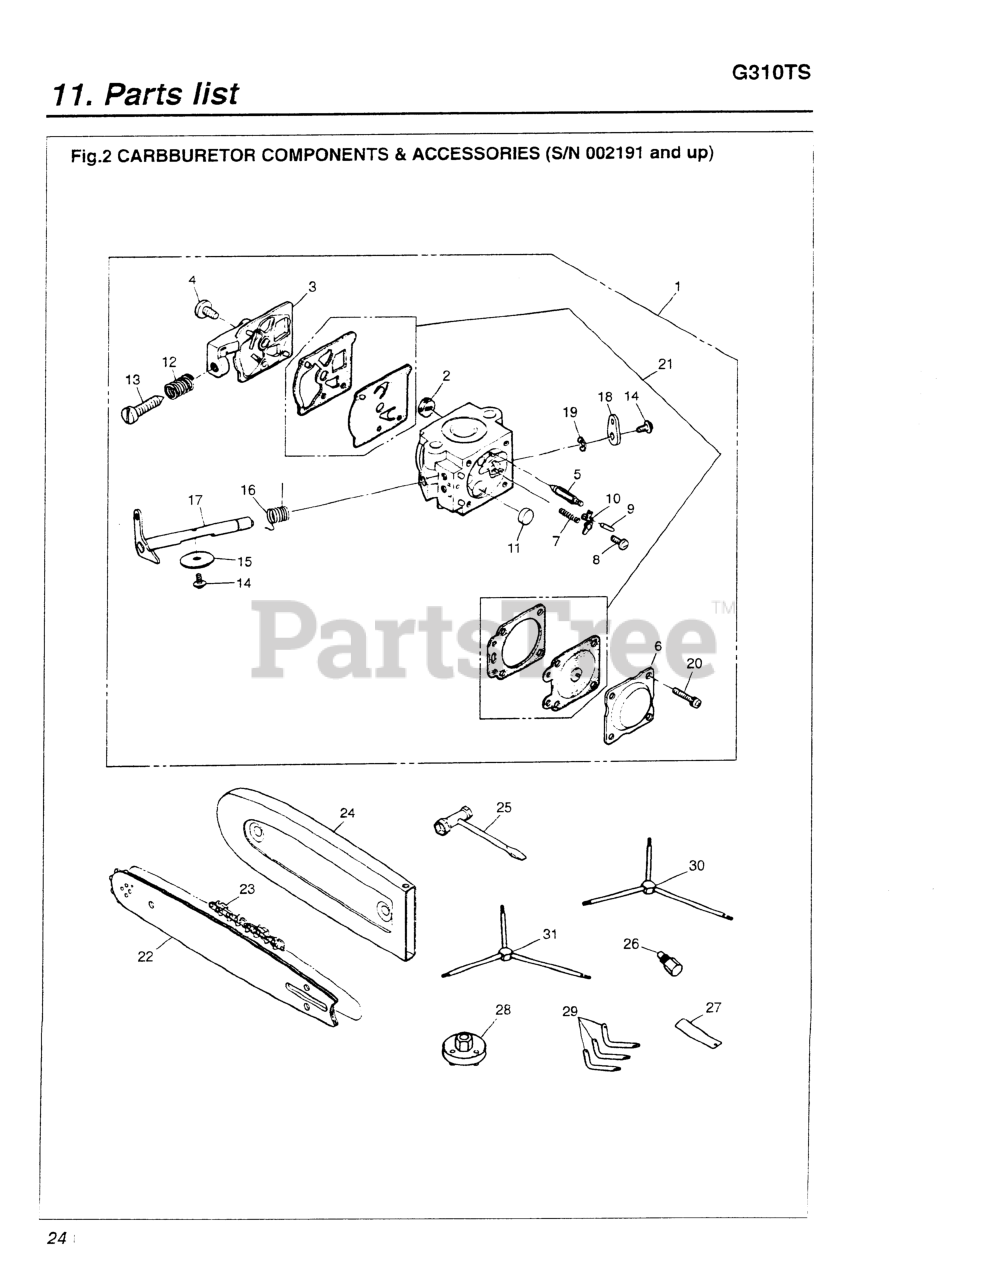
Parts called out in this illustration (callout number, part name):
1	CARBURETOR ASSY (RPLS -81000)
3	COVER, PUMP
5	VALVE, INLET
7	SPRING (RPLS 2841-81270)
9	PIN, METERING LEVER
10	LEVER
11	PLUG, WELSH
12	SPRING, IDLE
16	SPRING, RETURN
17	SHAFT ASSEMBLY
20	SCREW ASSEMBLY
22	BAR 14
24	PROTECTOR (14.5
25	WRENCH, PLUG
27	GAUGE (TOOL)
28	WRENCH (TOOL)
29	WRENCH (TOOL)
31	HEX WRENCH (TOOL)
